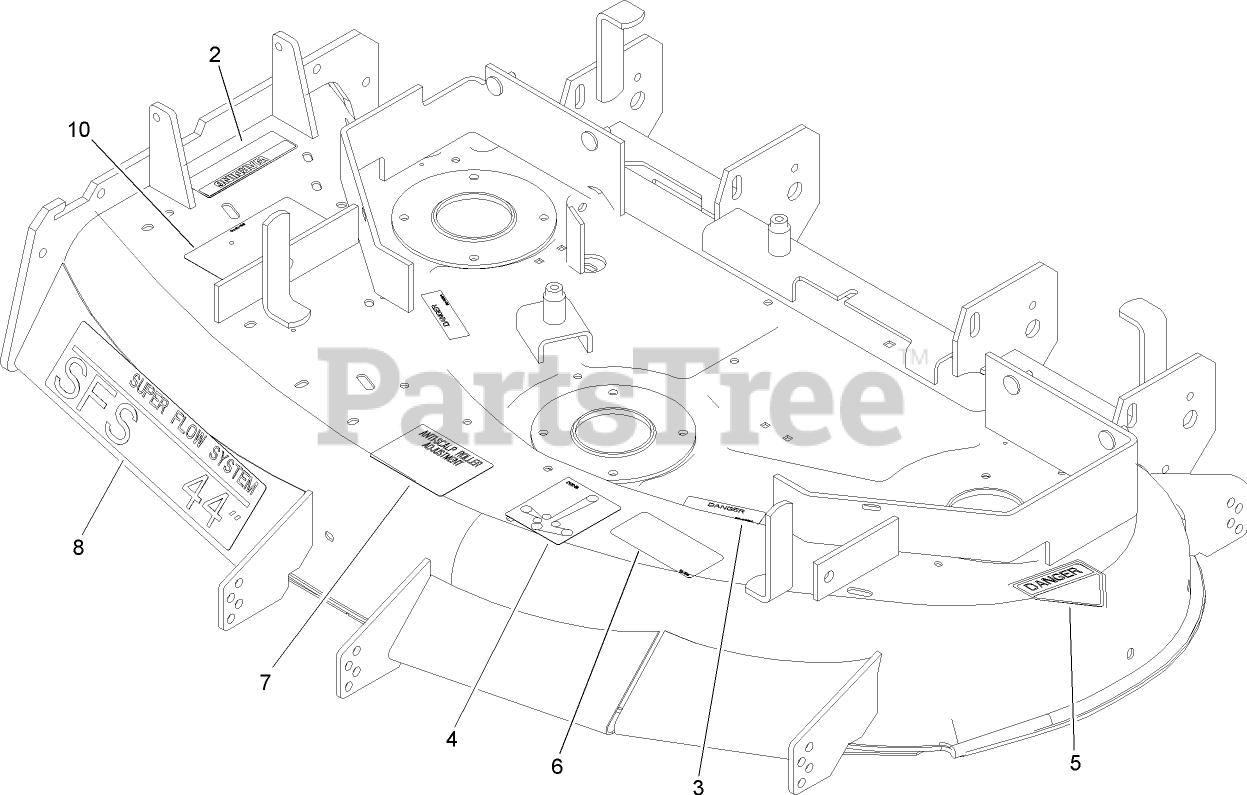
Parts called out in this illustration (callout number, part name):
2	DECAL-WARNING
3	DECAL-COVER, MISSING
4	DECAL-ROUTING, BELT
5	DECAL-DANGER
6	DECAL-TORQUE, BLADE BOLT
7	DECAL-WHEEL, GAGE
10	DECAL-DANGER, THROWN OBJECT
